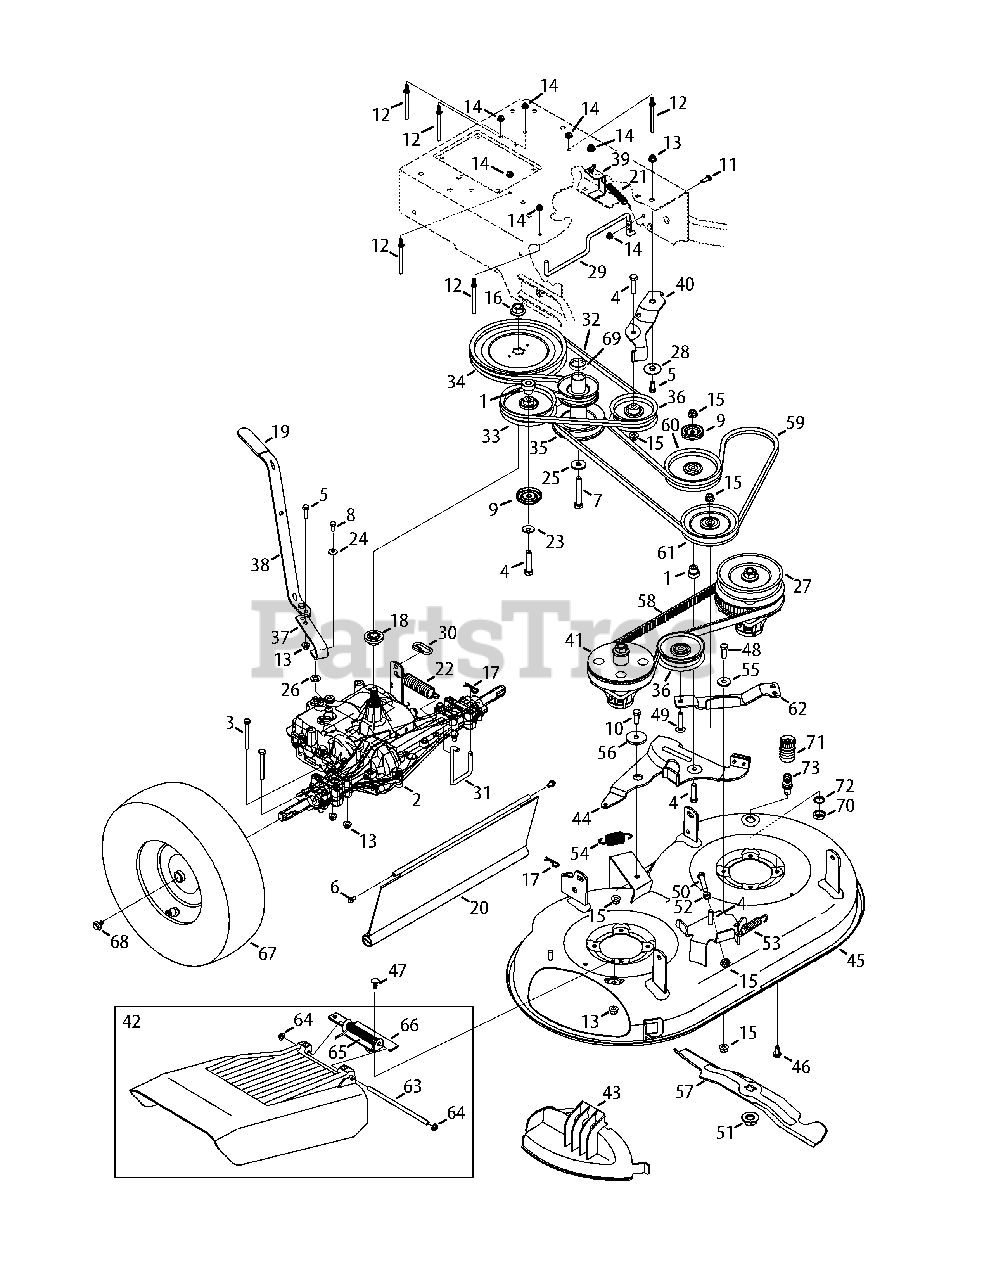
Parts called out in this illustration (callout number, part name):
1	Shoulder Spacer
2	4 Speed Drive Assembly, Tecumseh
3	Hex Head Cap Screw, 5/16-18 x 2.75
4	Hex Head Cap Screw, 3/8-16 x 1.75
5	Hex Head Cap Screw, 5/16-18 x 1.00
6	Screw, 10-16 x 0.625
7	HHCS, 7/16-20 x 3.00
8	Hex Head Cap Screw, 1/4-28 x .625
9	Pulley Cap
10	Hex Head Cap Screw, 3/8-16 x 1.25
11	Hex Head Cap Screw, 1/4-20 x .75
12	Belt Keeper, .25 DIA X 3.0
13	Flangelock Nut, 5/16-18
14	Flangelock Nut, 1/4-20
15	Flangelock Nut, 3/8-16
16	Flange Nut, 9/16-18
17	Click Pin, .092 x 1.64 LG
18	Spline Pulley Hub, 5/8
19	Grip, Black
20	Trailshield, 8.35 x 19.17
21	Extension Spring, Wheel Drive
22	Extension Spring, Brake
23	Washer, Spring, .401 x .870 x .063
24	Washer, Bell, .265 x .75 x .062
25	Washer, Flat, .450 x 1.250 x .164
26	Washer, Flat, .39 x .87 x .06
27	Drive Spindle Assembly
28	Spacer, Shoulder, .5000 x .1475
29	Belt Keeper Rod
30	Coupling Link, 3/16
31	Brake Spring Mounting Rod
32	V Belt. 4L 64.2
33	Idler Pulley, 4.25 DIA
34	Flat Sheave, DIA 7.75
35	Engine Pulley, 3.20 x 4.35 DIA
36	Idler Pulley, 3.50 DIA
37	Lower Shaft Lever
38	Upper Shaft Lever
39	Belt Keeper, .375 x 2.00
41	Spacer Spindle Assembly
42	Chute Deflector Assembly
43	Mulch Cover
44	Idler Arm Assembly
45	Deck Assembly
46	Screw, 5/16-18 x .750
47	Bolt, Carriage, 5/16-18 x .750
48	Hex Head Cap Screw, 3/8-16 x 1.00
49	Screw, Carriage, 3/8-16 x 1.69
50	Hex Head Cap Screw, 3/8-16 x 2.00
51	Flange Nut, 5/8-18
52	Hex Nut, 3/8-16
53	Extension Spring, Timing Belt
54	Extension Spring, Deck Brake
55	Shoulder Spacer, .625 ID x .169
56	Shoulder Spacer, .8840 x .190
57	2 in 1 Blade
58	Timing Belt, .315 x .787
59	Aramid V Belt, 72.2
60	Idler Pulley, 4.25" DIA
61	Idler Pulley, V-Type, 5.0 DIA
62	Timing Idler Bracket
63	Deflector Pin
64	Push Cap
65	Deflector Torsion Spring
66	Deflector Hinge Bracket
67	Wheel, 16 x 4 x 8
68	Screw, 5/16-24 x .750
69	Spacer, 1.0 x 1.28 x .31
70	Nut, Hex, M16-1.5
71	Water Nozzle Adaptor
72	Washer, Lock, 5/8
73	Deck Water Nozzle
